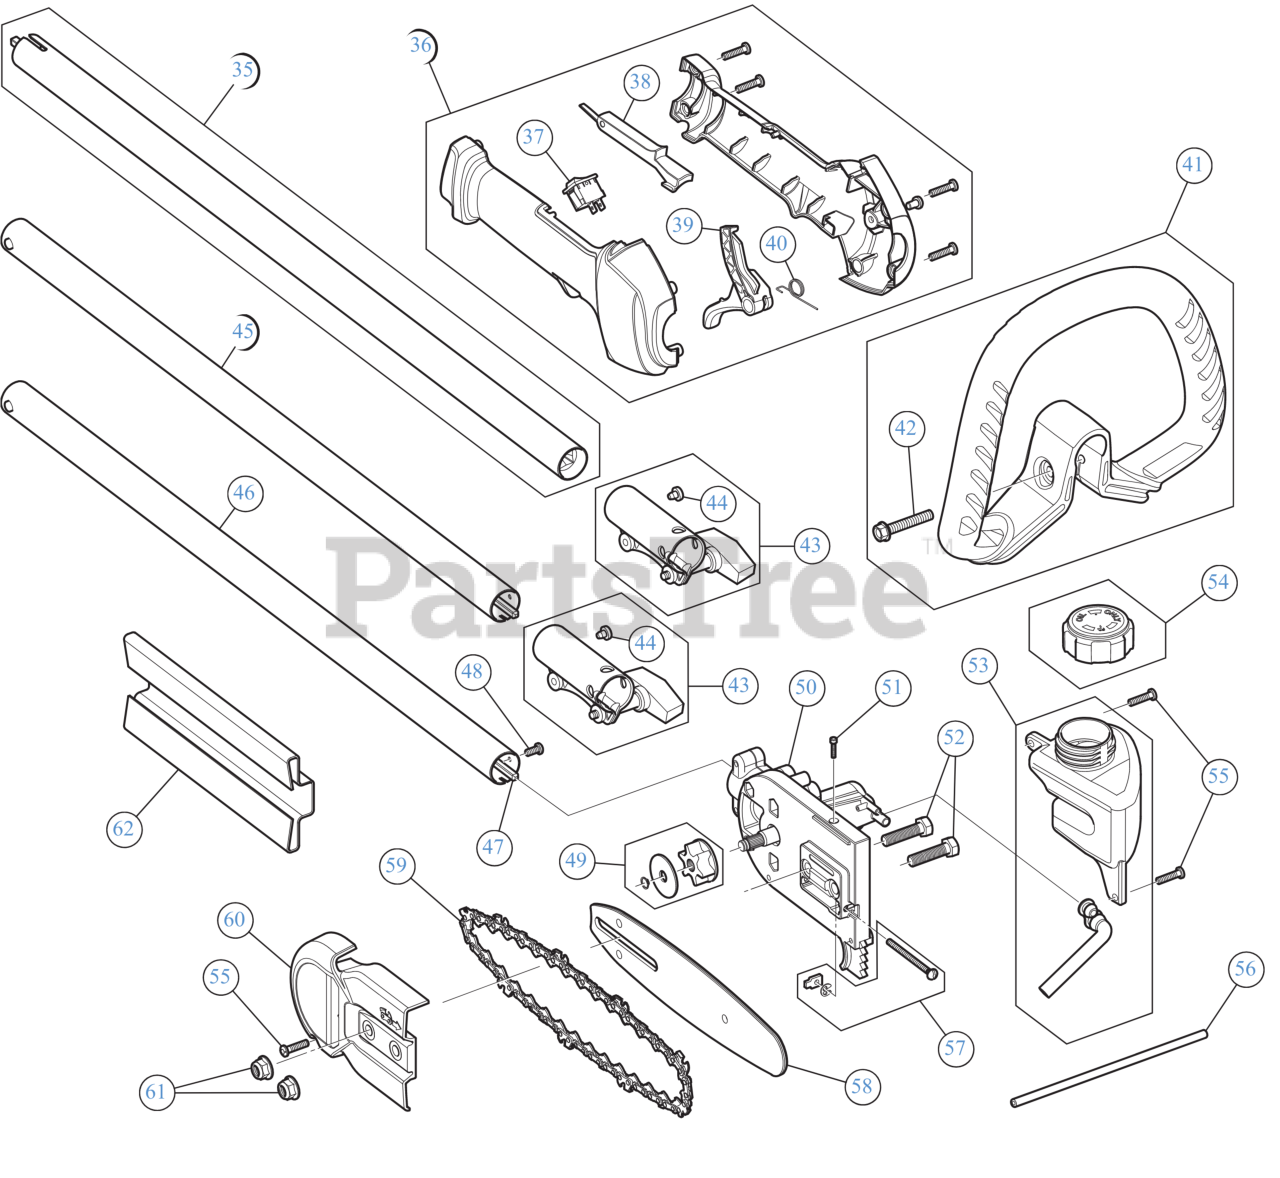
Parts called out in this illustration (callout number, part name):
35	BOOM ASSEMBLY UPR
36	THROTTLE GRIP ASSEMBLY
37	SW, MOMENTARY ON/O
38	LEVER LOCK OUT
39	THROTTLE TRIGGER
40	SPRING TRIG
41	HANDLE ASSEMBLY
42	BOLT 1/4-20X1 1/2
43	COUPLER ASSEMBLY
44	SCREW, 10-32X.250 TA
45	EXTENSION BOOM ASSEMBLY
46	BOOM ASSEMBLY 24"
47	LOWERIBLE DRIVE SHAFT
48	SCREW 1/4-20 X.500
49	SPROCKET ASSEMBLY
50	GEAR BOX ASSEMBLY
51	SCREW 4X40X.50
52	SCREW 5/16-18 x 1.25 GR5
53	OIL TANK ASSEMBLY
54	FUEL CAP ASSEMBLY
55	SCREW, #8-16X.750 PH
56	OIL LINE
57	CHAIN TENSION HDW
58	BAR 8" SPROCKET NOSE
59	CHAIN 8" 34 LINK .043 GAUGE
60	CHAIN GUARD
61	FLANGE LOCK NUT 5/16-18
62	CHAIN COVER
